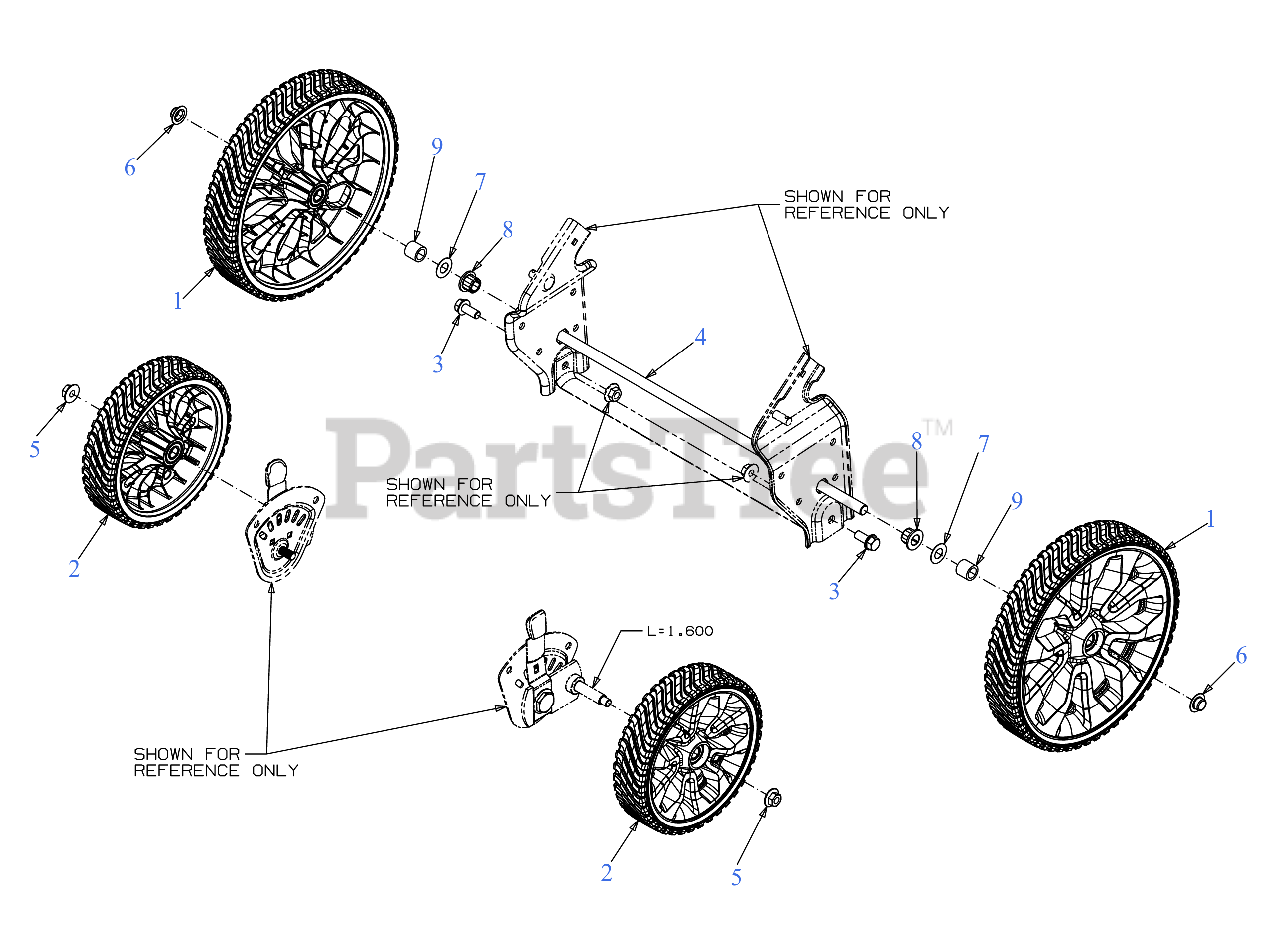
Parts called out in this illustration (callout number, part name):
1	WHEEL ASSEMBLY 11 x 2 GRAY BB
2	WHEEL ASSEMBLY 8 x 2 GRAY BB
3	SCREW 3/8-16 x .875 GR5
4	REAR AXLE .50 x 22.53 CSV
5	FLANGE LOCK NUT
7	FLAT WASHER
8	HEX FLANGE BEARING .506ID x .590LG
9	SPACER-.513 ID x .703 OD x .69
